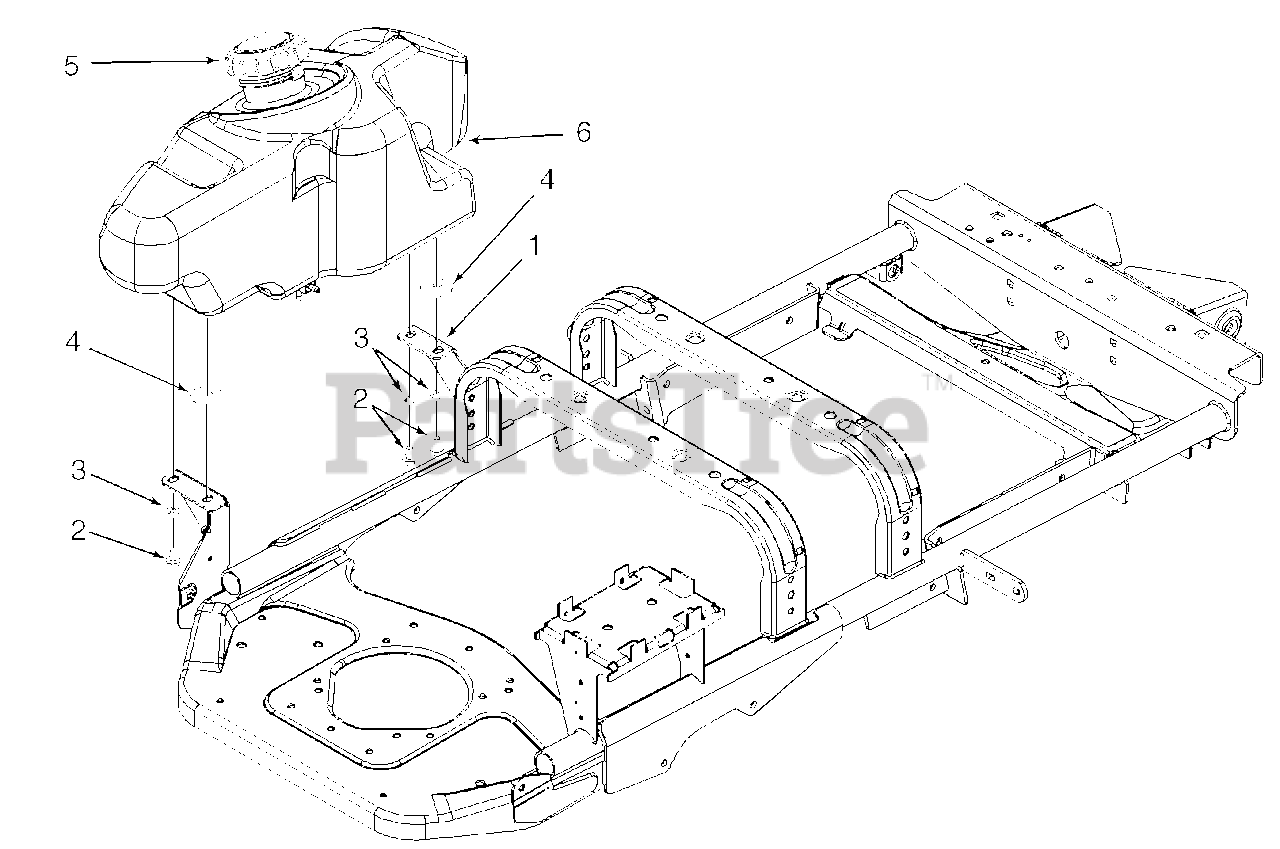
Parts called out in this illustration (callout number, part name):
1	Bracket, Fuel Tank Mounting
2	Screw, Hex Cap, 3/8-16 x .62 GR5
3	Washer, Lock, 3/8
4	Washer, Flat, .390 x 1.5 x .10
5	Cap, Fuel
